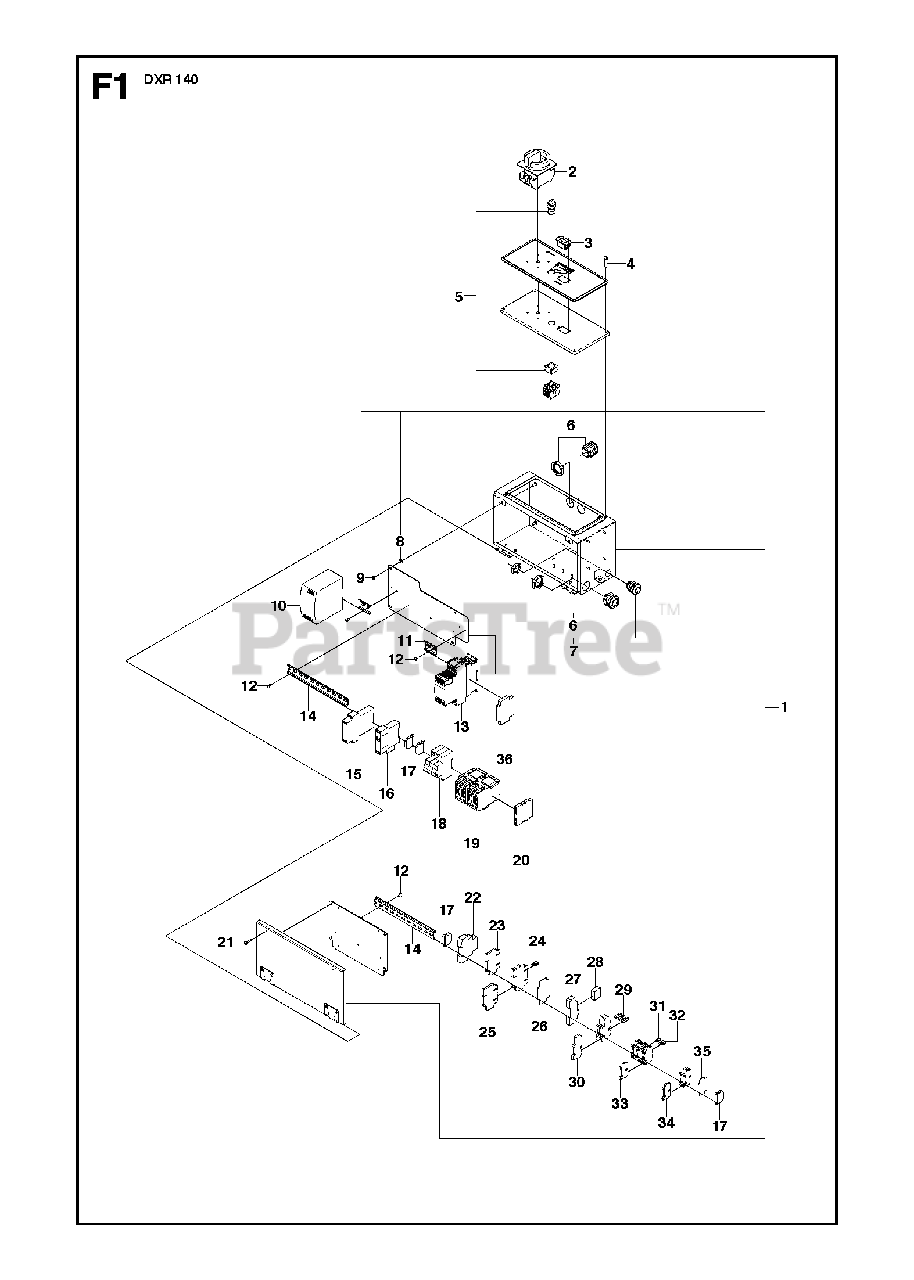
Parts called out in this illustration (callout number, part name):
4	SCREW EHHM
15	RELAYB1, Safety relay
16	RELAYK1, Phase sequence relay
22	CONTROLT3, Fan control relay
25	RELAYK2, K3, K4, K5, K7
